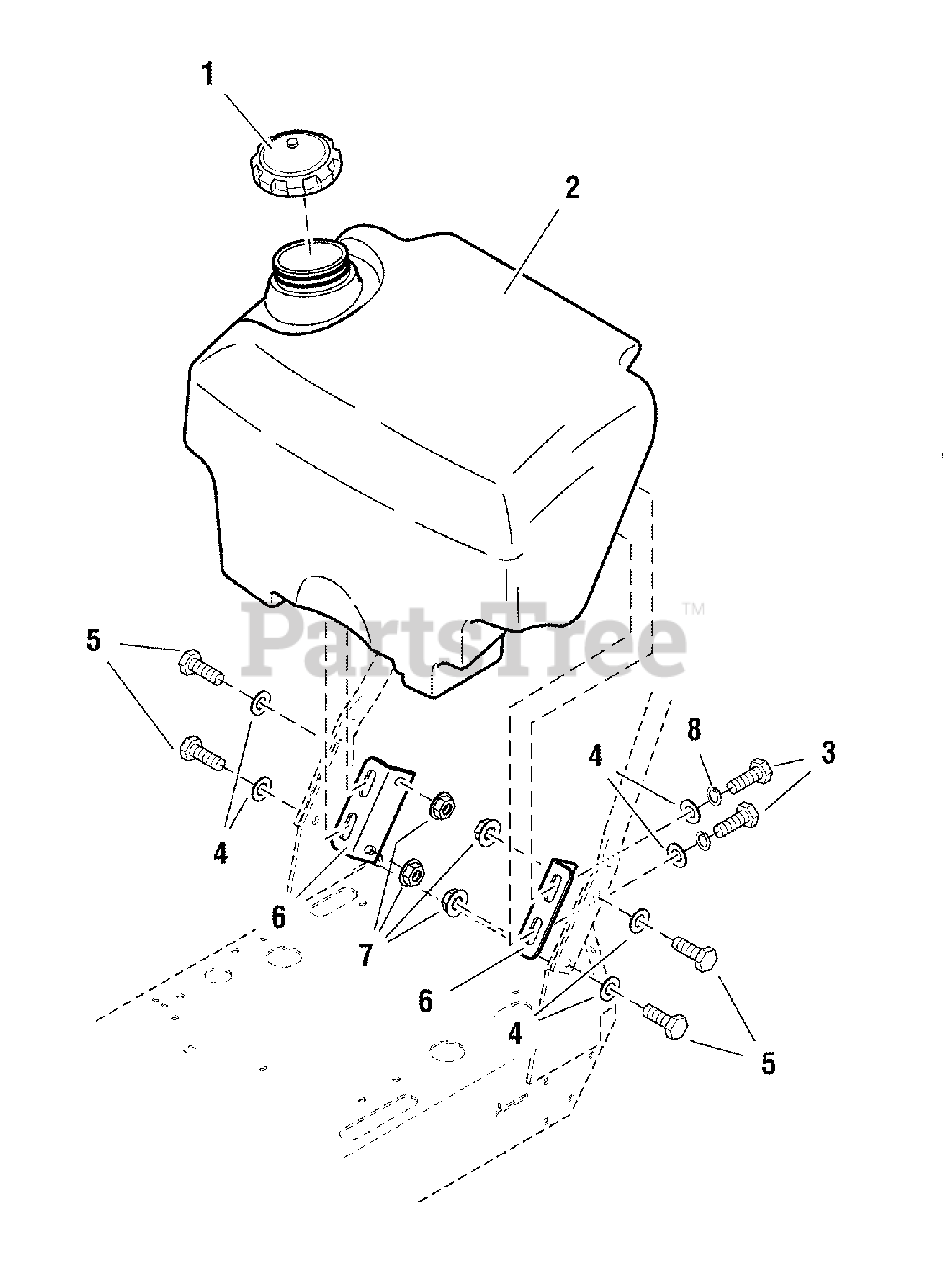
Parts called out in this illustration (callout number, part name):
1	CAP, FUEL TANK, 3-1/2" NECK
2	TANK, FUEL
3	BOLT, 3/8-16 X 3/4" GD5 CZ
4	WASHER, 3/8 SAE
5	BOLT, 3/8-16 X 1-1/4" GD5 CZ
6	MOUNT, FUEL TANK
7	NUT, 3/8-16 HEX NYLOCK FLANGE
8	WASHER, 3/8" SPLIT LOCK
